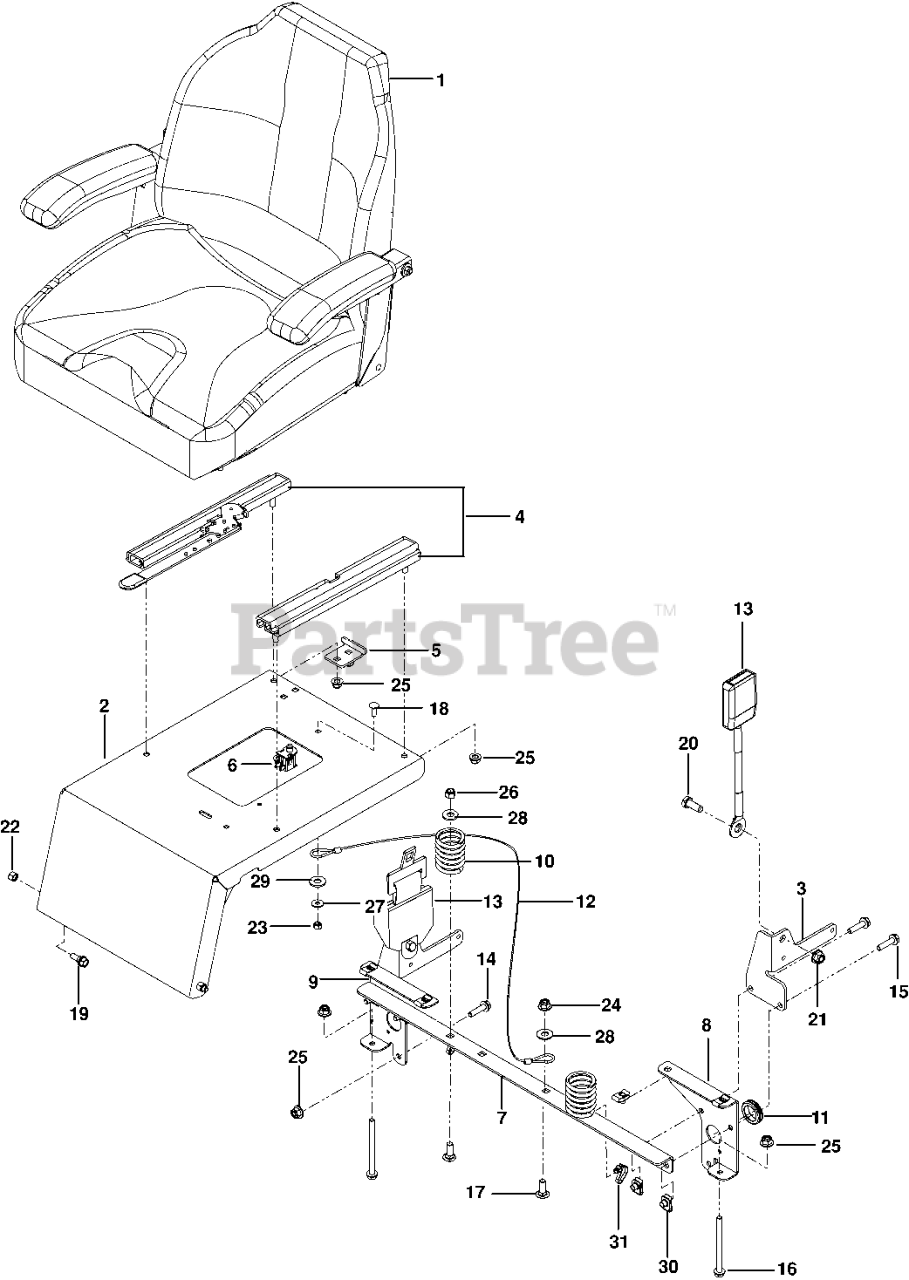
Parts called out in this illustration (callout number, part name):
1	SEAT.907.VINYL.HUSQVARNA
2	KIT.SEAT.MOUNT.W/DECAL
3	MOUNT, SEAT BELT, BLACK
4	4"SINGLE LOCK TRACK SET W/HDWR
5	STOP, SEAT - BLACK
6	SEAT SWITCH
7	SUPPORT, SEAT
8	SUPPORT, RT, BLK
9	SUPPORT, LT, BLK
10	SPRING, SEAT
11	RUBBER GROMMET
12	SEAT LANYARD
13	Seat Belt, Retractable
14	HHFS 5/16-18 X 3/4
15	HHFS 5/16-18 X 1.25 TPBLT GD 5
16	HHFS 5/16-18 X 3 3/4
17	RHSNB 3/8C X 1
18	RHSNB 1/4C X 3/4
19	SB 5/16-18 HEX HD GD5, BLK ZN
20	SCREW 7/16-20 X 1 HHB GR5
21	NUT HEX 7/16F LOCK RP
22	NUT 5/16 NYLOC
23	NUT.1/4-20.HEX.NYLOC.ZD
24	NUT 3/8-16 HEX FLG NYLOC ZD
25	5/16-18 NYLOC FLANGE NUT
26	NUT 3/8-16 NYLOC
27	WASHER 1/4 FLAT
28	WASHER 3/8 FLAT
30	U-CLIP 5/16-18 NUT RETAINER
31	TIE WRAP, 8-3/8", W/CLIP
